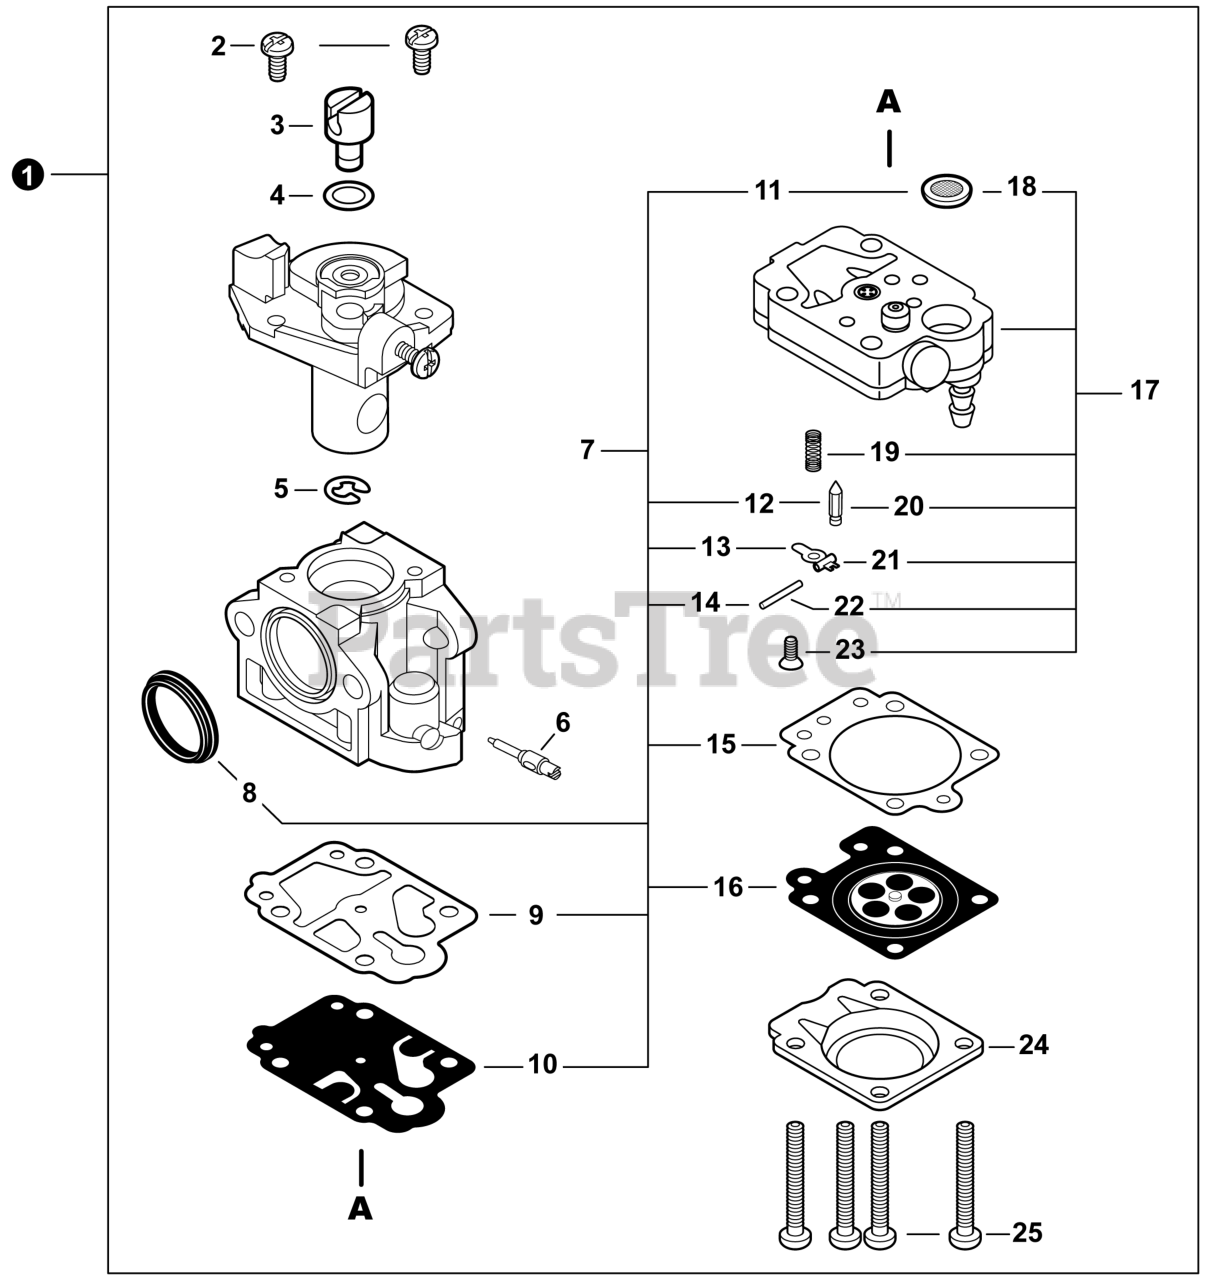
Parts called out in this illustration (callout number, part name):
1	CARBURETOR - WYK-345
6	NEEDLE, HIGH SPEED
7	REPAIR KIT, CARBURETOR
8	RING, PACKING
9	GASKET, PUMP
10	DIAPHRAGM, FUEL PUMP
11	SCREEN, FUEL INLET
12	VALVE, INLET NEEDLE
13	LEVER, METERING
14	PIN, METERING LEVER
15	GASKET, METERING DIAPHRAGM
16	DIAPHRAGM, METERING
17	BODY ASSY, PUMP
18	SCREEN, FUEL INLET
19	SPRING, METERING LEVER
20	VALVE, INLET NEEDLE
21	LEVER, METERING
22	PIN, METERING LEVER
23	SCREW
24	COVER, METERING DIAPHRAGM
